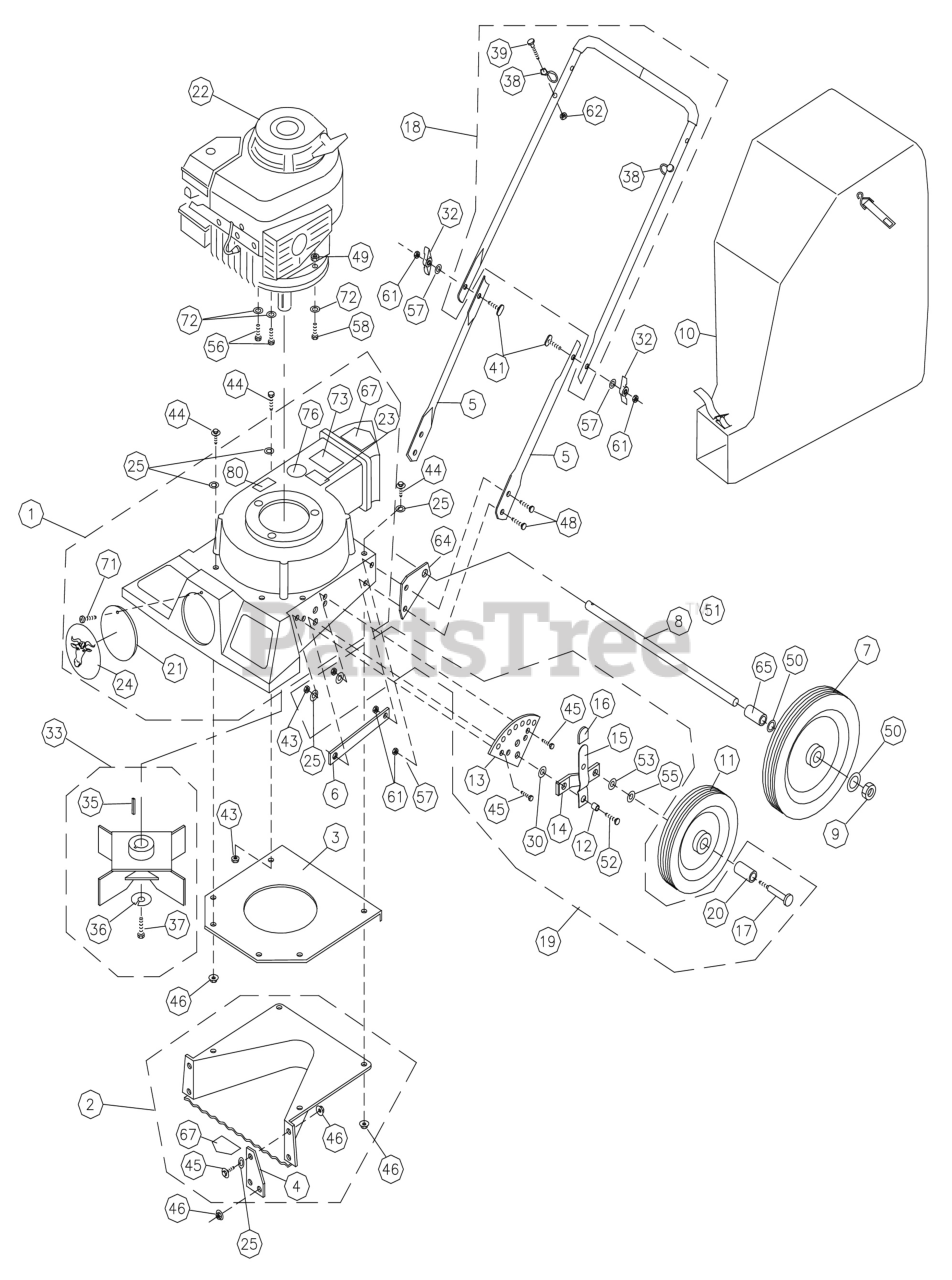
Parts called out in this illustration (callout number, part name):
1	HOUSING ASSY LB GREEN
2	SEE: 900596-04
3	PLATE MIDDLE INLET
4	PLATE MOUNTING
5	HANDLE LOWER LB
6	PLATE BACKUP
7	WHEEL & TIRE ASSY 10" SEMI PN
9	NUT LOCK 1/2"-13 NYLON INSERT
10	BAG ASSY LB (SEE ACCESSORY PRICELIST)
11	WHEEL & TIRE ASSY 8" SEMI PN
13	PLATE HT ADJ
14	AXLE ARM HT ADJ
15	ARM ASSY HT ADJ
16	GRIP TIP HT ADJ
17	SCREWCAP 3/8"-16X2 1/2" HCS ZP
18	HANDLE UPPER ASSY W/GRIP
19	HT ADJ ASSY LBQ
20	SPACER WHEEL FRONT
21	PLUG HOUSING PLAIN GREEN
22	SEE: BRIGGS & STRATTON DEALER
23	SEE: 100346
24	LABEL LOGO SMALL FRAME
25	WASHER 1/4"SAE9/32"X5/8"X1/16"
26	SCREWCAP 5/16"-18X1 1/4" HEX ZP
30	WASHER 1/2" FLAT KD WHEEL MTG
32	KNOB LOCKING 5/16" NC BLACK
33	SEE: 900422
35	KEY 3/16" SQ X 1 1/4"
36	WASHER LOCK 3/8" S/T MED
37	SCREWCAP 3/8"-24 X 1" HCS GR 8
39	SCREWCAP 1/4"-20X1 1/4" HCS ZP
41	BOLT CARRIAGE LB
43	NUT LOCK 1/4"-20 HEX Z/P
44	SCREWCAP 1/4"-20 X 1" HCS ZP
45	SCREWCAP 1/4"-20X3/4" HCS ZP
46	NUT LOCK 1/4"-20 WASH FACE
48	SCREWCAP 5/16"-18X1 1/4" HEX ZP
49	NUT LOCK 5/16"-18 HEX Z/P
50	WASHER 1/2" SAE Z/P
52	SCREWCAP 3/8" - 16 X 1/2" HCS ZP
53	WASHER LOCK 3/8"INTERNAL
55	WASHER 3/8"SAE 13/32"X13/16"X1/16"
56	SCREWCAP 5/16"-18X1 1/2" HCS ZP
57	WASHER 5/16" SAE Z/P
58	SCREWCAP 5/16"-18X2 1/2" HCS ZP
61	NUT LOCK 5/16"-18 HEX Z/P
62	NUT LOCK 1/4"-20 HEX Z/P
64	BRACKET AXLE
65	SPACER 1\2" X 5\8"
67	LABEL WARNING OPEI
71	SCREW SELFTAP #10-24 X 1/2" HMS ZP
72	WASHER 5/16" FLATWASHER Z/P
73	LABEL DANGER FLYING DEBRIS
76	LABEL LOCKING
